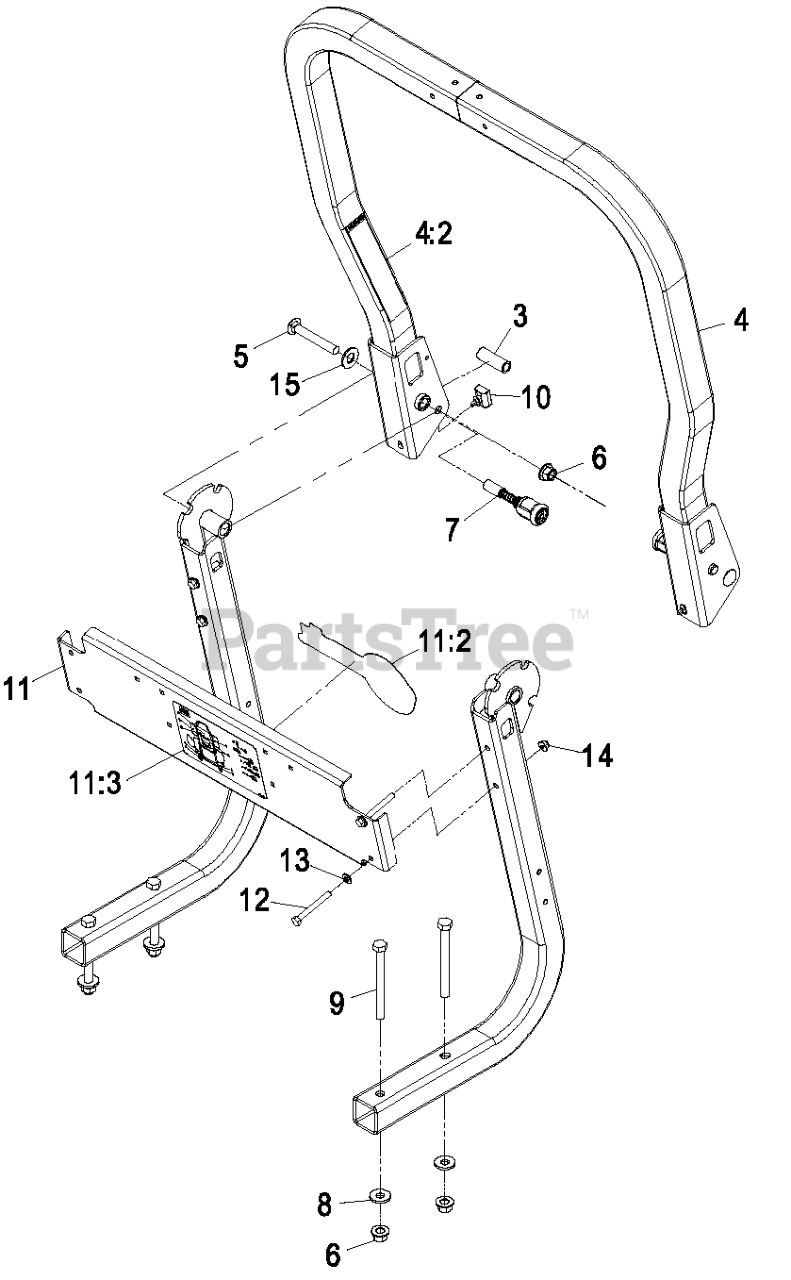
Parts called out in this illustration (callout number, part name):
4	UPPER ROPS ASM- W/ DECAL
4:2	DECAL-WARNING, FOLDING RO
5	SCREW-CARR
6	Nut-Lock 1/2-13
7	PIN-SPRING
8	WASHER-SPRING
9	SCREW-HH
10	BUMPER-ROPS
11:2	DECAL, EXMARK LOGO
11:3	DECAL-SERVICE AID
12	SCREW-HH
13	WASHER-SPRING
14	NUT-HF, NI
15	WASHER-FLAT
